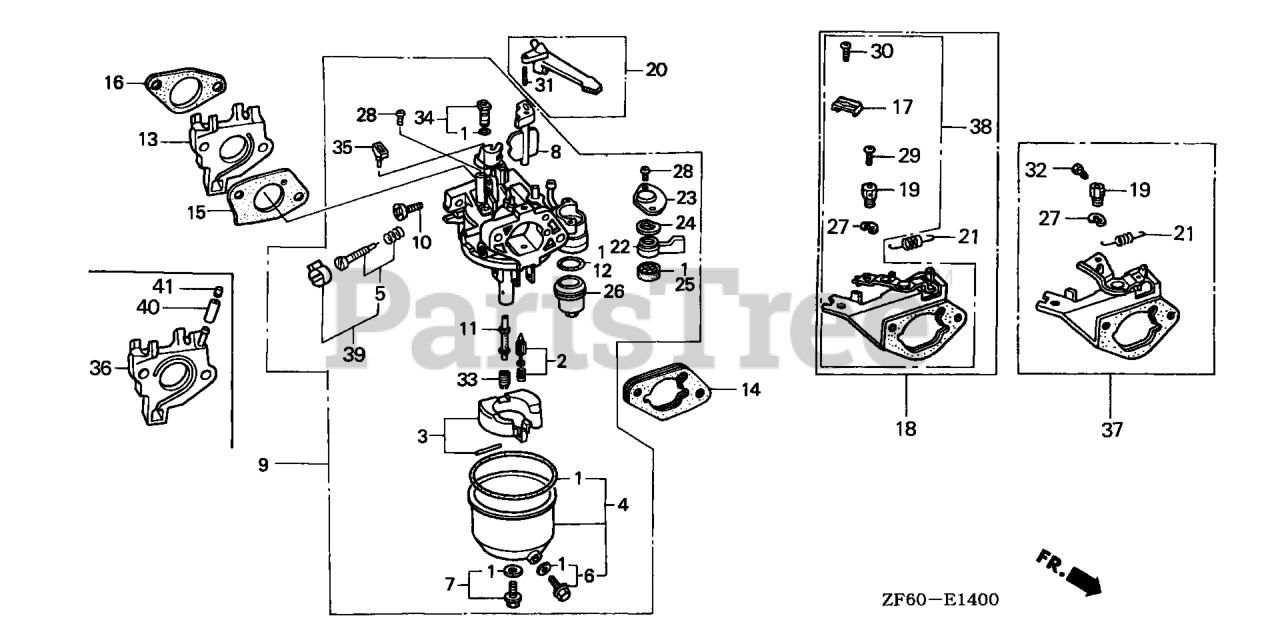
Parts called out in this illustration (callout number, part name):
1	GASKET SET (INCLUDE 16173-001-004) (INCLUDES 16173-001-004)
2	VALVE SET, FLOAT
3	FLOAT SET
4	CHAMBER SET, FLOAT
5	SCREW SET, PILOT (Honda Code 1441500). (CARBURETOR NO.)
6	SCREW SET, DRAIN (Honda Code 1672187). (CARBURETOR NO.)
7	SCREW SET B
7	SCREW SET
8	CHOKE SET (CARBURETOR NO.)
9	CARBURETOR ASSY. (BE48B B)
10	SCREW, THROTTLE STOP
11	NOZZLE, MAIN (CARBURETOR NO.)
12	GASKET, FUEL STRAINER CUP
13	INSULATOR, CARBURETOR
14	SPACER, CARBURETOR
15	GASKET, CARBURETOR
16	GASKET, INSULATOR Use up to Engine SN 2949254.
20	LEVER, CHOKE (STD)
22	LEVER, VALVE
23	PLATE, LEVER SETTING (CARBURETOR NO.)
24	SPRING, PETCOCK LEVER (CARBURETOR NO.)
25	GASKET, VALVE
26	CUP, FUEL STRAINER
28	SCREW, PAN (3X6)
28	SCREW, PAN (3X8) (CARBURETOR NO.)
31	PIN, SPRING (2X12)
33	JET, MAIN (#100) Use up to Engine SN BE50A A.
33	JET, MAIN (#102) (CARBURETOR NO.)
33	JET, MAIN (#105) (CARBURETOR NO.)
34	JET SET, PILOT (#40)
34	JET SET, PILOT (#40) (ADVENTURE GREEN) (CARBURETOR NO.)
